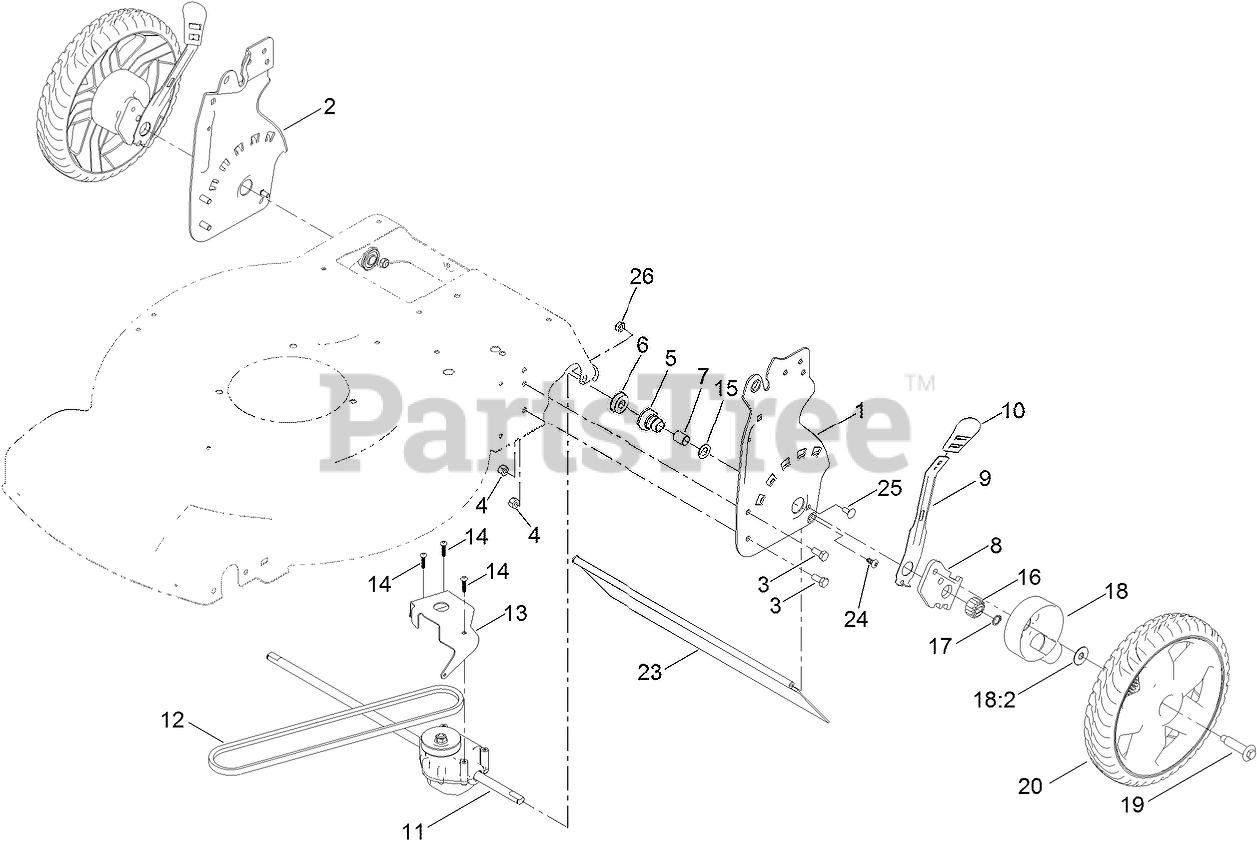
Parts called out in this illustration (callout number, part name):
1	PLATE-HOC, RWD (LH)
2	PLATE-HOC, RWD (RH)
3	SCREW-HH
4	NUT-HEX
5	RETAINER-BUSHING, HOC
6	BEARING-BALL
7	BUSHING-SLEEVE
8	ARM-PIVOT, REAR
9	ARM-SPRING
10	KNOB-HOC
11	TRANSMISSION-RWD (6:1)
12	BELT-V
13	BRACKET-TRANSMISSION
14	SCREW-PLASTITE
15	WASHER-THRUST
16	GEAR-PINION, 15T
17	RING-RETAINING
18	GEAR COVER ASM
18:2	WASHER-STEPPED
19	BOLT-SHOULDER
20	WHEEL GEAR ASM, 11IN
23	SHIELD-TRAILING
24	SCREW-THD
25	BOLT-CARR
26	NUT-LOCK
